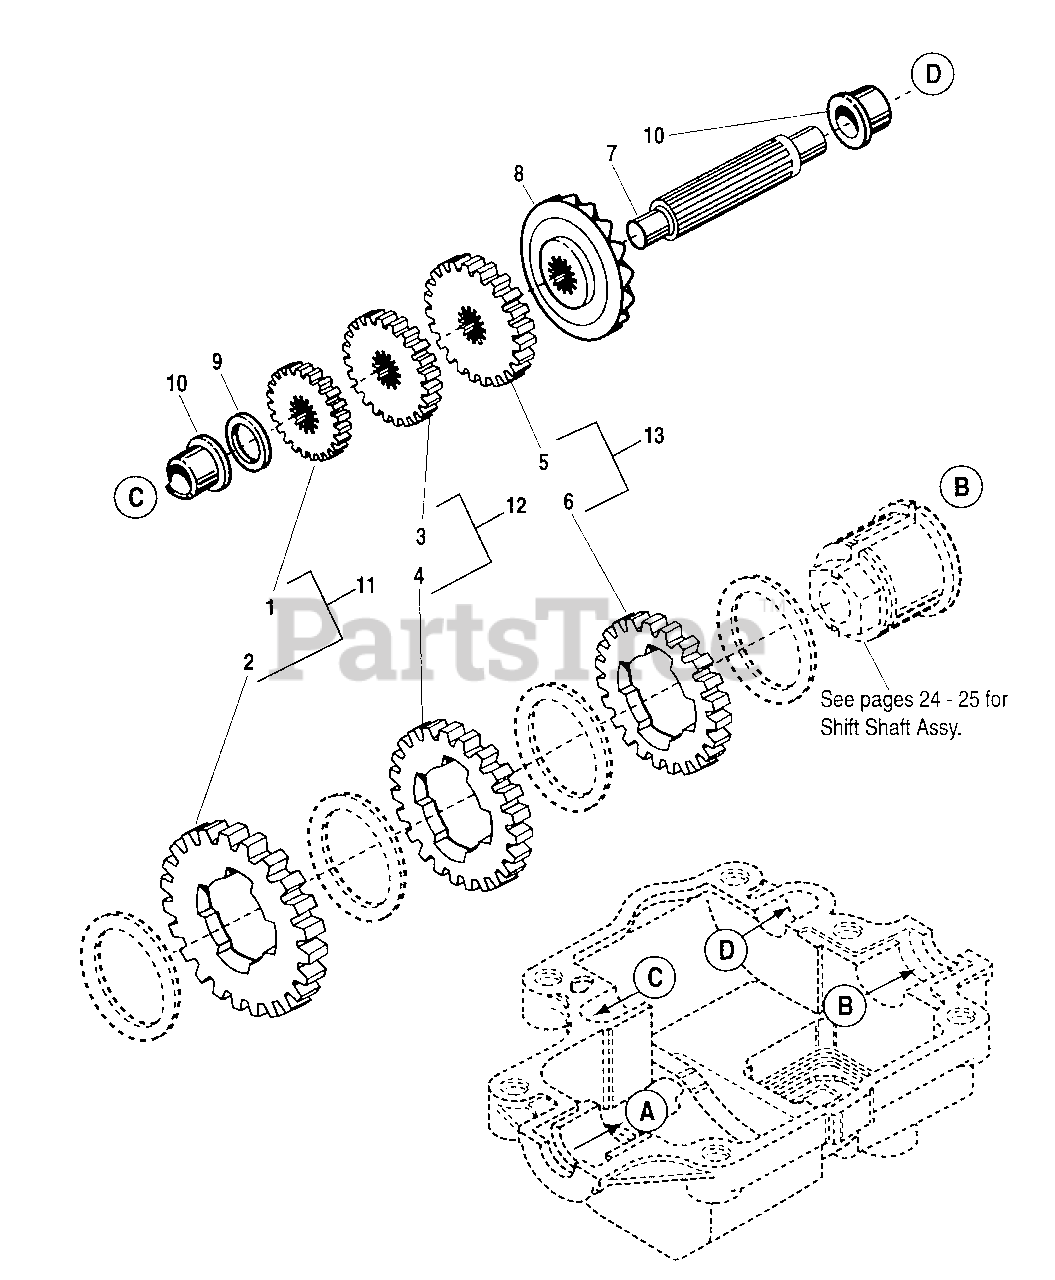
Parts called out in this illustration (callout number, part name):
7	SHAFT, Reduction
10	BUSHING SET (not available individually)
11	GEAR SET (Incl. Ref. Nos. 1 & 2)
12	GEAR SET (Incl. Ref. Nos. 3 & 4)
13	GEAR SET (Incl. Ref. Nos. 5 & 6)
